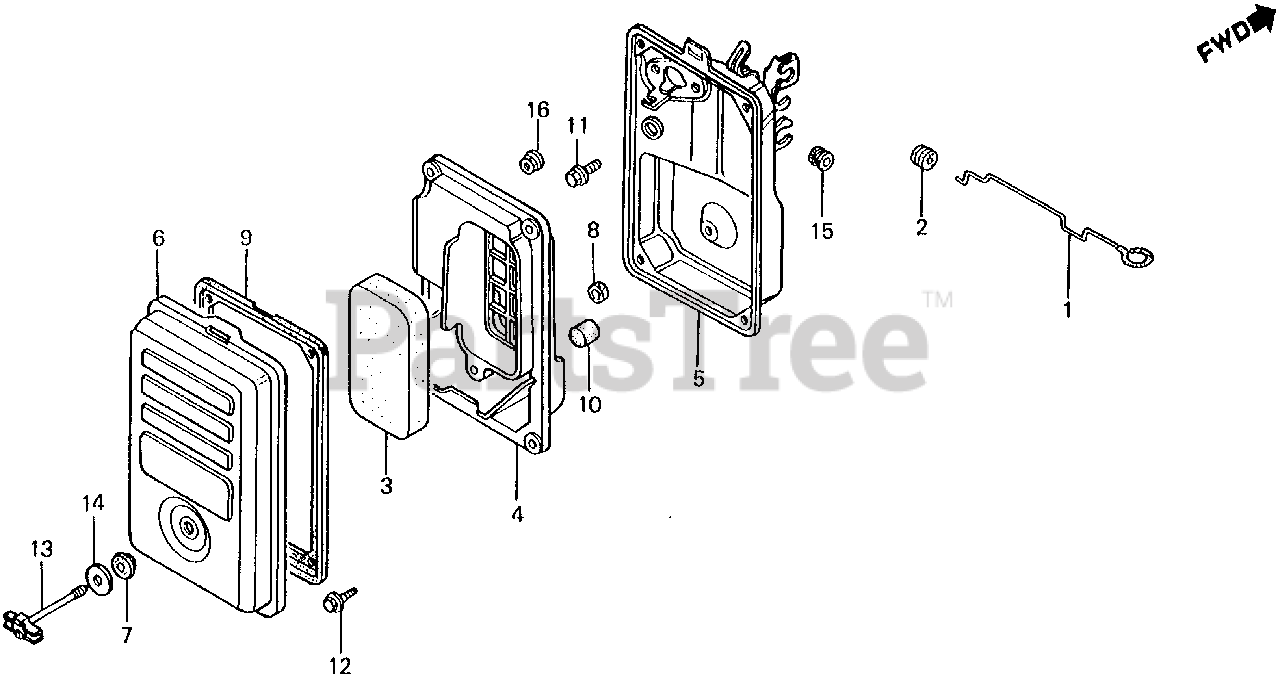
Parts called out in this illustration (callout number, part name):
1	ROD, CHOKE CONTROL
2	GROMMET, CHOKE ROD
3	ELEMENT, AIR CLEANER
4	SEPARATOR, AIR CLEANER (NOT AVAILABLE)
5	HOUSING, AIR CLEANER
6	COVER, AIR CLEANER (NOT AVAILABLE)
7	GROMMET, AIR CLEANER
8	RUBBER, DUST SEAL
9	SEAL, AIR CLEANER
10	FILTER, DRAIN TUBE
11	BOLT, FLANGE (8X16)
12	BOLT, SETTING
13	BOLT, AIR CLEANER COVER (8X58) (NOT AVAILABLE)
14	WASHER, AIR CLEANER
15	RUBBER, CONTROL BOX
16	NUT, FLANGE (6MM)
